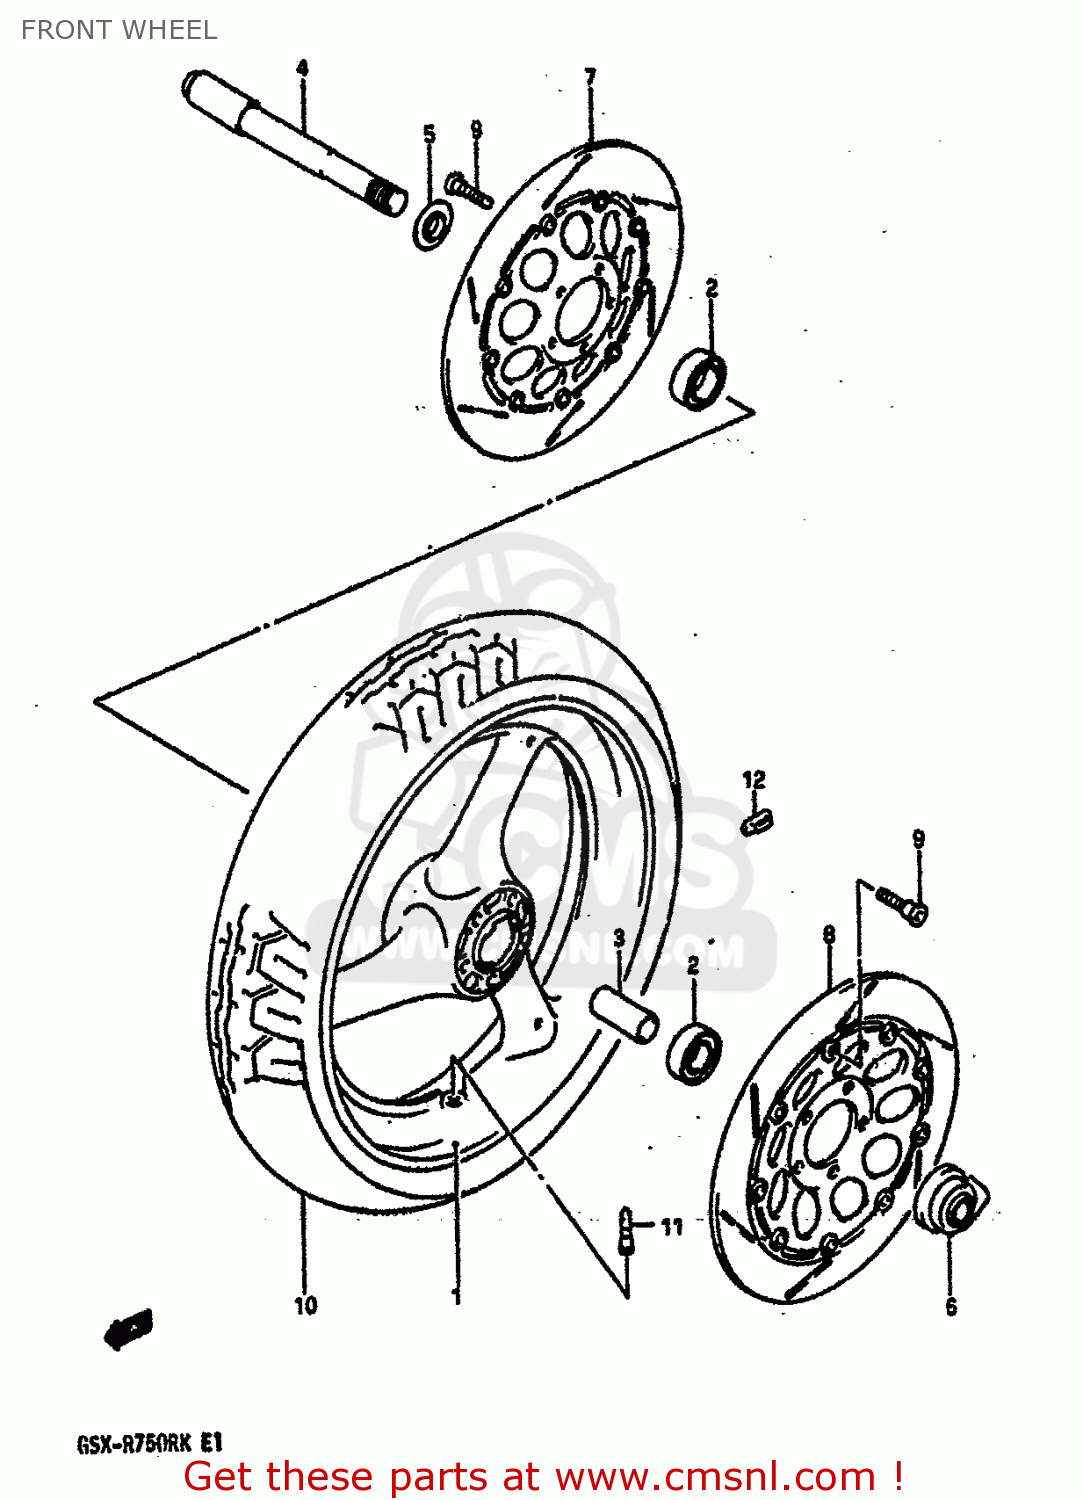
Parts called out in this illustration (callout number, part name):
1	WHEEL,FRONT
2	BEARING
3	SPACER(20.8X27.2X74)
4	AXLE,FR
5	SPACER,FR HUB BEARING,R
6	BOX ASSEMBLY,SPEEDOMETER GEAR
7	DISC,FRONT BRAKE RH
8	DISC,FRONT BRAKE LH
9	BOLT
10	TAPE,FRONT (120/70 ZR17)
11	VALVE ASSY,WHEEL RIM(TR412)
12	BALANCER,WHEEL
